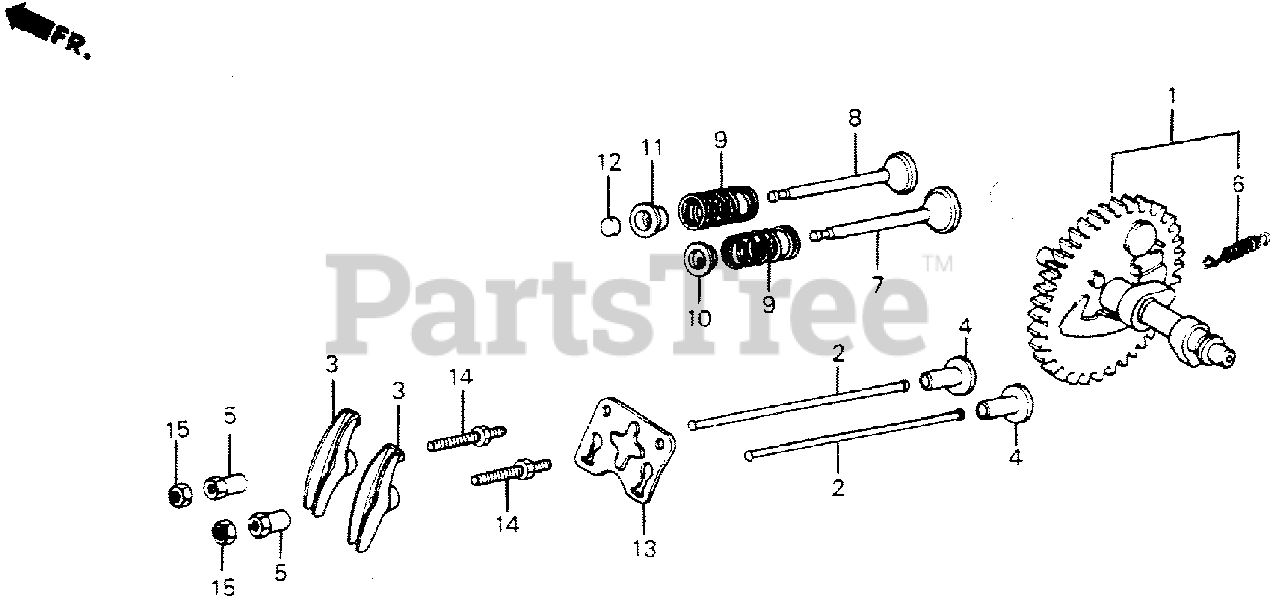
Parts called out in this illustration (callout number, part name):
1	CAMSHAFT ASSY.
2	ROD, PUSH
3	ARM, VALVE ROCKER
4	LIFTER, VALVE
5	PIVOT, ROCKER ARM
6	SPRING, WEIGHT RETURN
7	VALVE, IN.
8	VALVE, EX.
8	VALVE, EX. (STELITE)
9	SPRING, VALVE
10	RETAINER, IN. VALVE SPRING
11	RETAINER, EX. VALVE SPRING
12	ROTATOR, VALVE
13	PLATE, PUSH ROD GUIDE
14	BOLT, PIVOT (8MM)
15	NUT, PIVOT ADJ.
